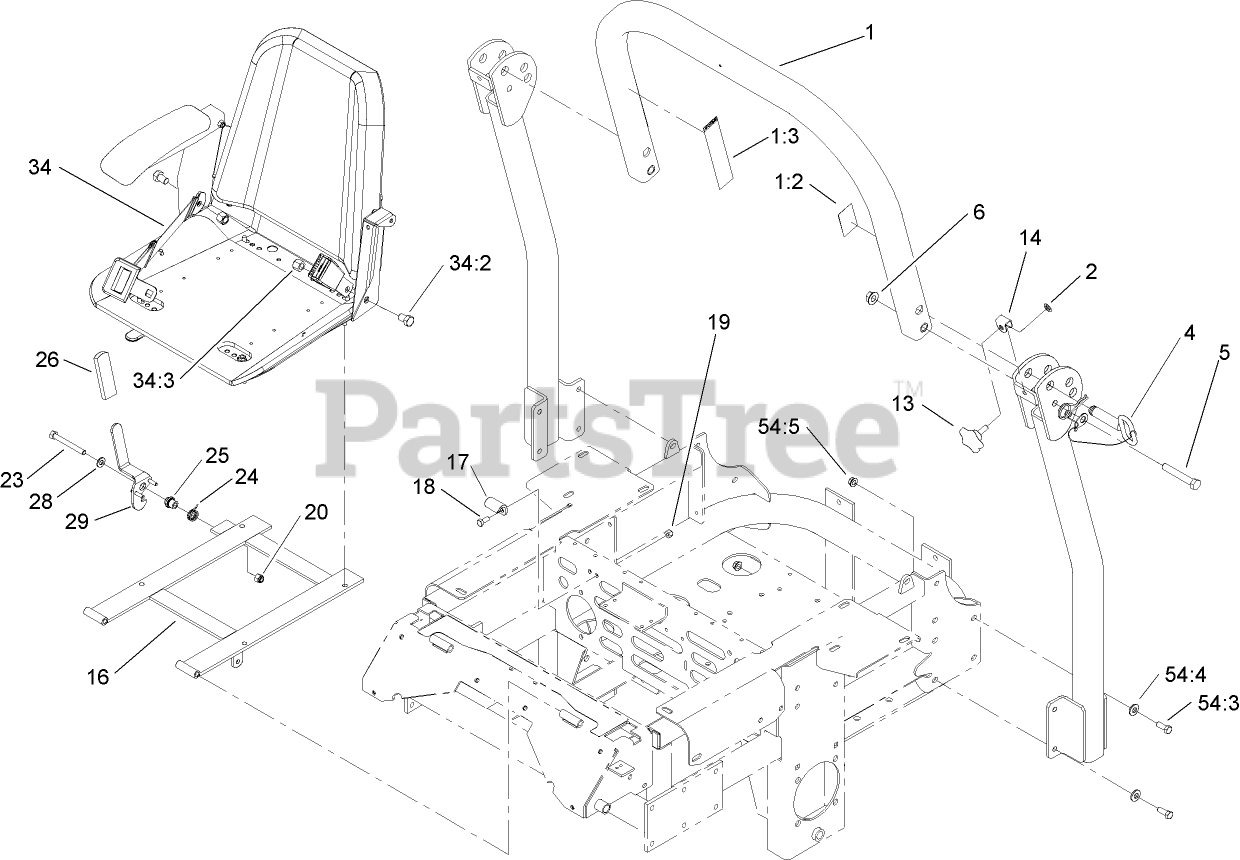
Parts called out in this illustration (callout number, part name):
1	Upper Tube ASM
1:2	DECAL-ROPS
1:3	DECAL-WARNING, FOLDING ROPS
2	NUT-PUSH
4	PIN-FOLD, ROPS
5	SCREW-HH
6	NUT-HF
16	SEAT SUPPORT FRAME ASM
17	Catch-Latch, Seat
18	SCREW-HH
19	NUT-LOCK, NI
20	NUT-LOCK, NI
23	SCREW-HH
24	SPRING-TORSION
25	BUSHING-LATCH, SEAT
26	GRIP-HANDLE
28	WASHER-FLAT
29	LATCH ASM
34	SEATBELT KIT
34:2	SCREW-HH
34:3	NUT-LOCK, NI
54:3	SCREW-HH
54:4	WASHER-BELLEVILLE
54:5	NUT-HHF, WHIZ
